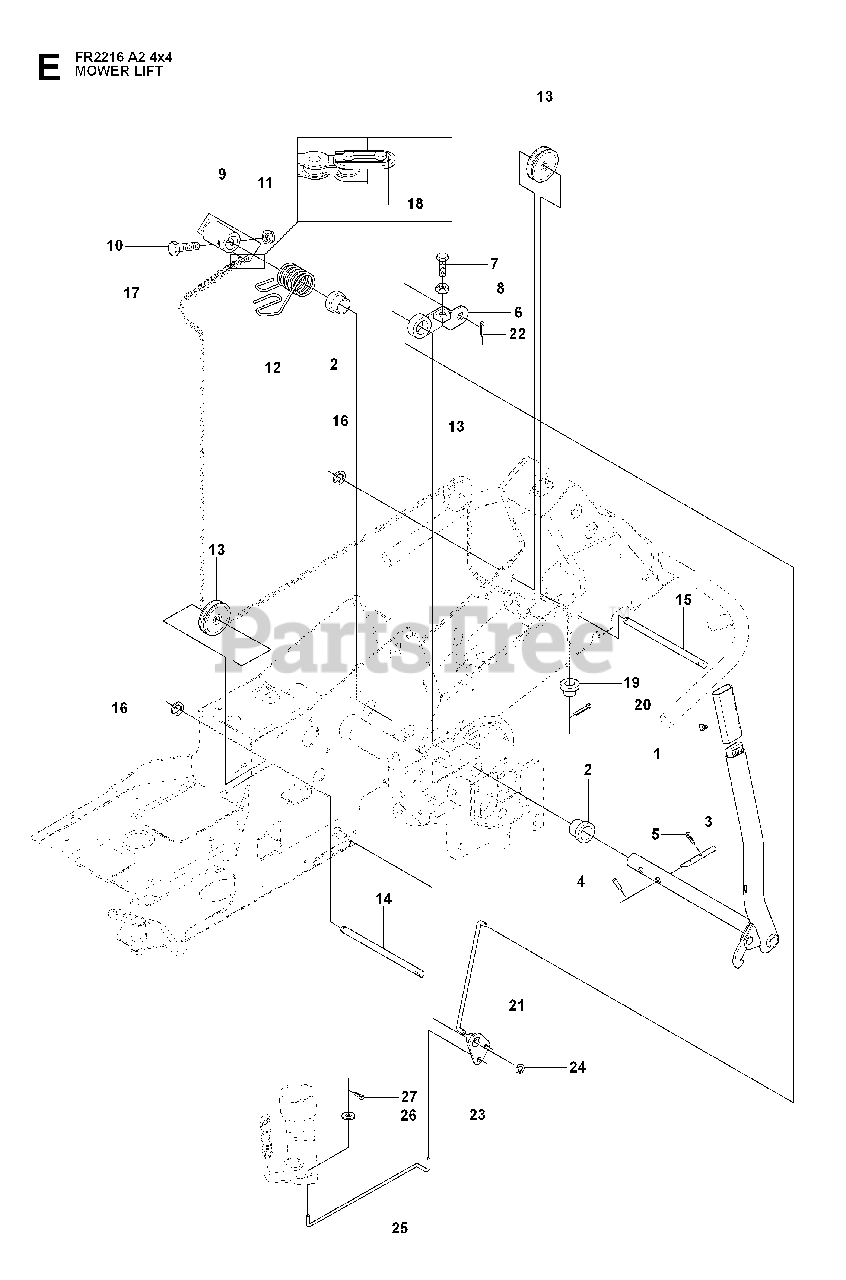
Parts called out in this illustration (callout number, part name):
1	LIFTING LEVER ASSY
2	BUSH
3	RP PIN
5	SPLIT PIN
6	LEVER CLUTCH
16	LOCK RING
20	COTTER PIN
21	CONNECTION ROD
22	SPLIT PIN
24	RETAINING RING
25	CONNECTION ROD
27	SPLIT PIN
